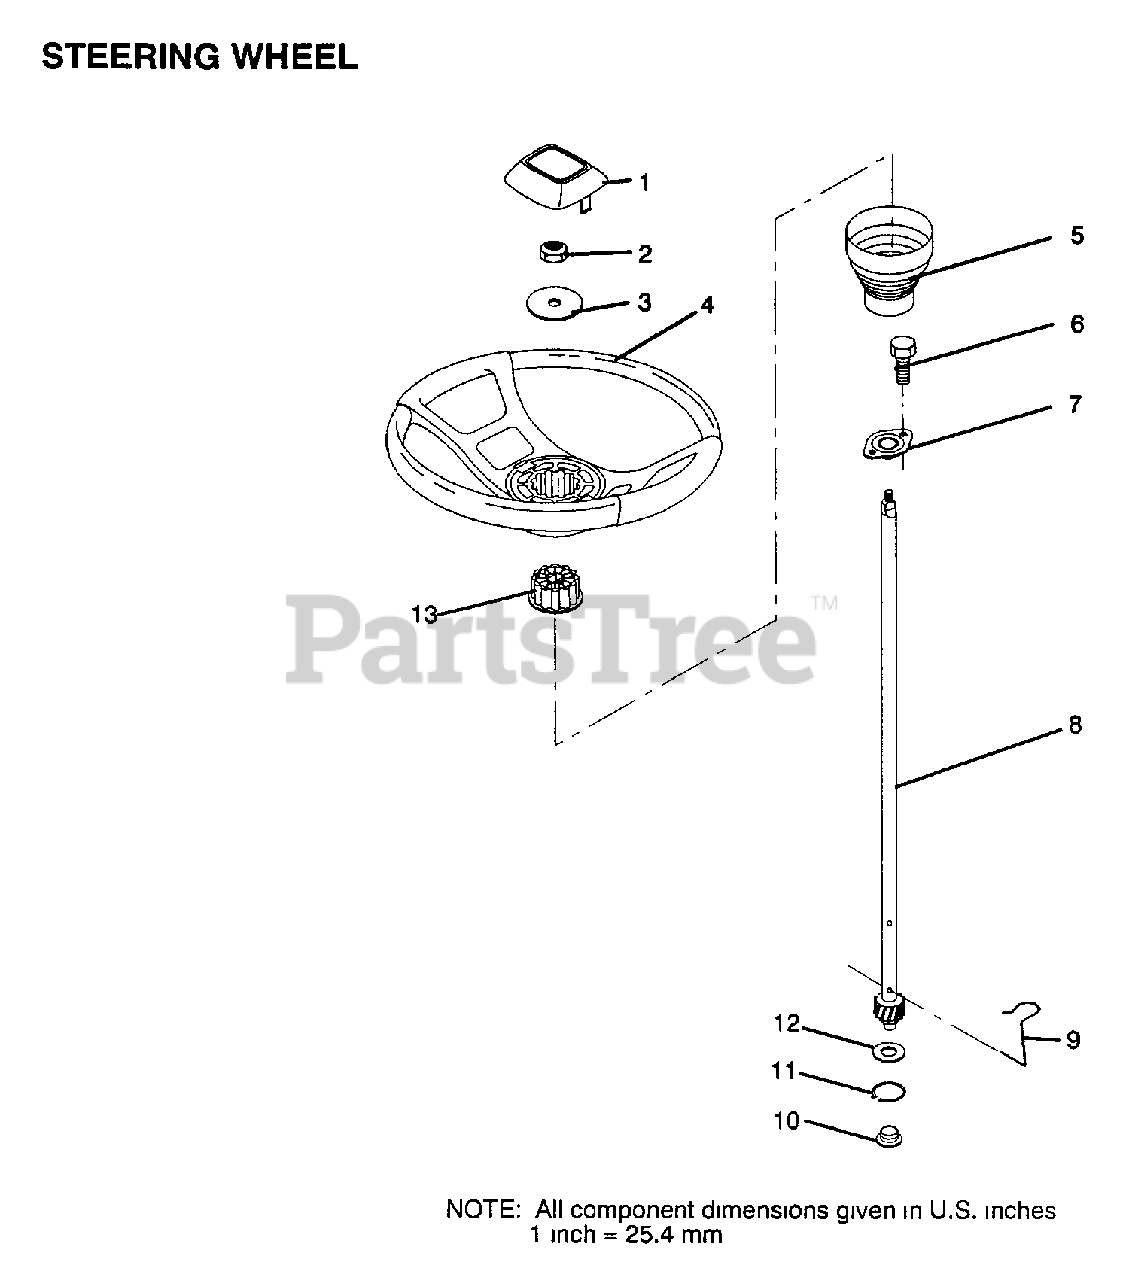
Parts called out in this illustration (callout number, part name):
1	INSERT-WHEEL LT
2	GRIPCO NUT
3	WASHER T
5	SLEEVE STEERING
9	STEERING CLIP
10	BUSHING STEER LWR
11	RING
12	WASHER LT
13	ADAPTER-WHEEL LT
